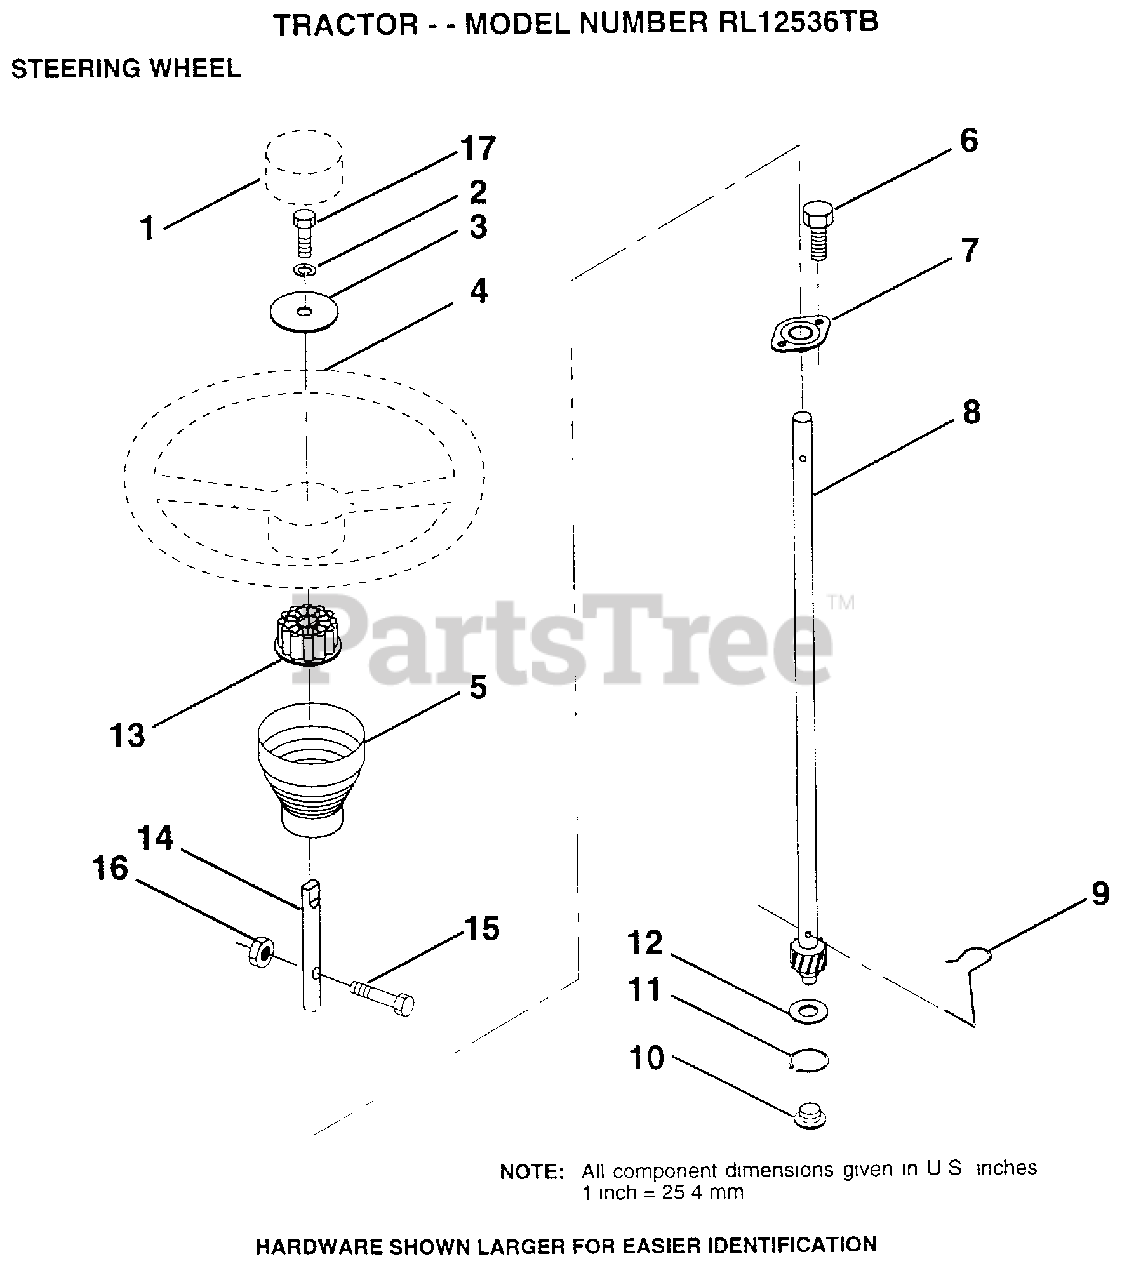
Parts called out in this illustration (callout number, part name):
1	ST WHL INSERT CAP
2	LOCKWASHER
3	WASHER T
5	SLEEVE STEERING
6	"SCREW-TT,10-32 FL"
8	SHAFT.STEERING.LR
9	STEERING CLIP
10	BUSHING STEER LWR
11	RING
12	WASHER LT
13	ADAPTER LT
14	EXT SHAFT STEERIN
15	BOLT
16	NUT
